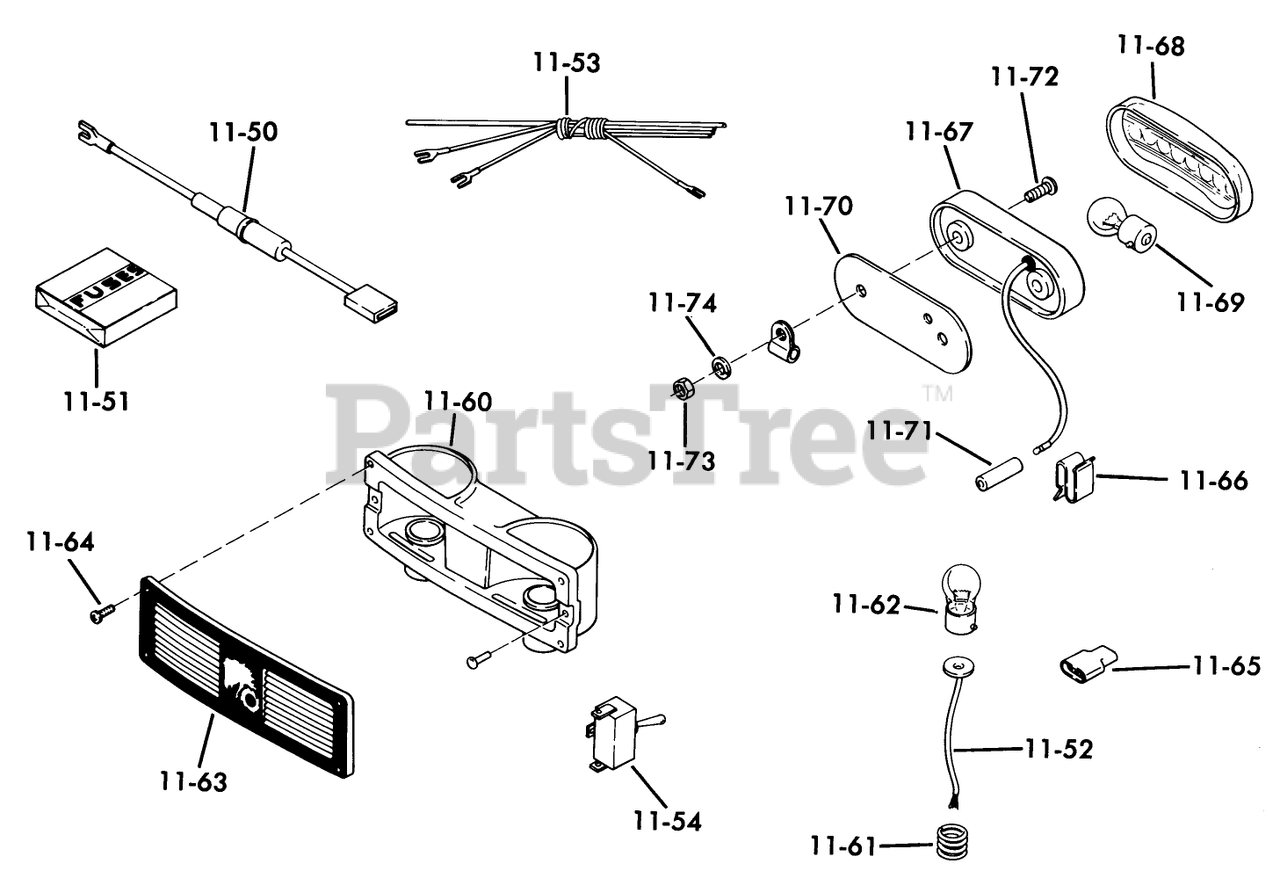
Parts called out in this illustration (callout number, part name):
11-50	ASSY FUSED CONNECTOR
11-52	WIRE ASSY
11-53	Wire Harness-Lights
11-54	SWITCH-LIGHTS
11-60	ASSY REFLECTOR HOUSI
11-61	SPRING
11-62	BULB
11-63	Lens
11-64	Pan HD Swage
11-65	CONNECTOR 3 WIRE
11-66	SPEED CLIP
11-67	Base
11-68	Lens
11-69	Bulb
11-70	Mounting Pad
11-71	CONNECTOR 2 WIRE
11-72	Screw
11-73	Nut
11-74	Lockwasher
